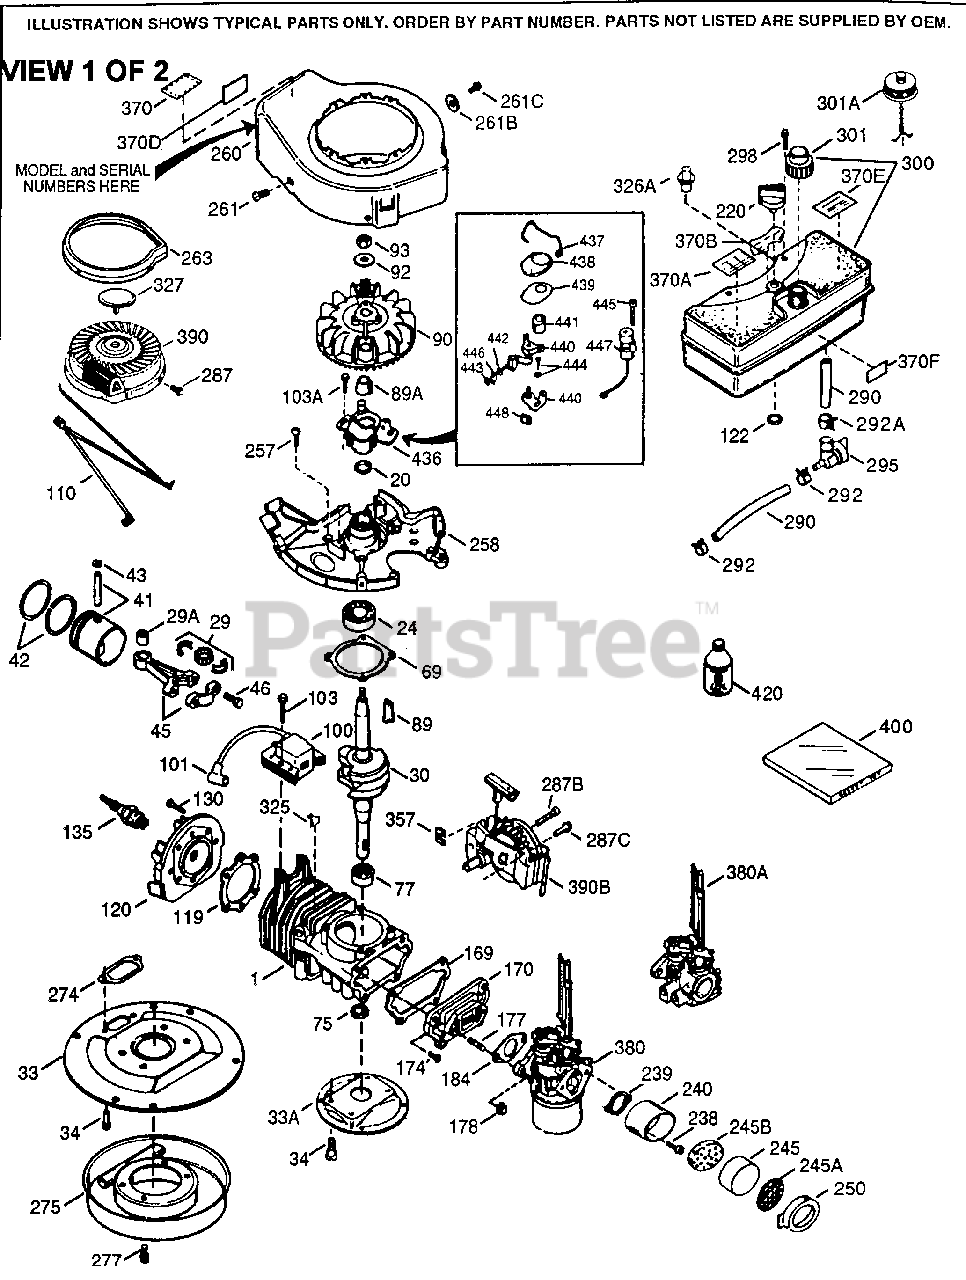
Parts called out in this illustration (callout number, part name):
1	"Cylinder Order S/B if replacement isn eeded
20	Oil Seal
24	Ball Bearing
29	Needle Bearing & Liner Set 37 Needles
29A	Cartridge Bearing
30	Crankshaft
33	Adapter Plate
34	Screw, 5/16-18 x 1/2"
41	Piston & Pin Ass'y. (Incl. 43)
42	Ring Set
43	Piston Pin Retaining Ring
45	Connecting Rod Ass'y. Incl. 29, 29A& 46
46	Connecting Rod Bolt
69	* Cylinder Cover Gasket
75	Oil Seal
77	Cartridge Bearing
89A	Adapter Sleeve
90	Flywheel
92	Belleville Washer
93	Flywheel Nut
100	Solid State Ignition
101	Spark Plug Cover
103	Screw, Torx T-15, 10-24 x 1"
110	Ground Wire
119	* Cylinder Head Gasket
120	Cylinder Head
122	Retaining Ring
130	Screw, Torx T-30, 1/4-20 x 3/4"
135	Resistor Spark Plug - RJ17LM
169	* Cover Plate Gasket
170	Reed & Cover Plate (Incl. 178)
174	Screw, Torx T-25, 10-24 x 1/2"
178	Nut & Lock Washer 1/4-28
184	* Carburetor Gasket
220	Control Knob
238	Screw, 10-32 x 5/8"
240	Air Cleaner Body
245	Air Filter
245B	Air Filter
250	Air Cleaner Cover
257	Screw, Torx T-30, 1/4-20 x 5/8"
258	Blower Housing Base (Incl. 20)
260	Blower Housing
261	Screw, 1/4-20 x 7/16"
261C	Screw, 1/4-20 x 1/2"
274	Exhaust Gasket
275	Muffler
277	Screw, Torx T-30, 1/4-20 x 5/8"
287	Screw, 8-32 x 21/64"
290	Fuel Line
292	Fuel Line Clamp
298	Screw, 10-32 x 7/8"
300	Fuel Tank (Incl. 301)
301	Fuel Cap
327	Starter Plug
370	Fuel Mix Decal
370A	Control Decal
370B	Warning Decal
370D	Instruction Decal
380	Carburetor (Incl. 184)
390	Rewind Starter
400	* Gasket Set (Incl. items marked PK in notes) (Incl. one each of part #'s:51 0110A, 510217A, 510227A, 510268A,5102 70A, 510274A, 510292A, 510323A
420	2-Cycle Oil with Fuel Stabilizer - 8 oz.
